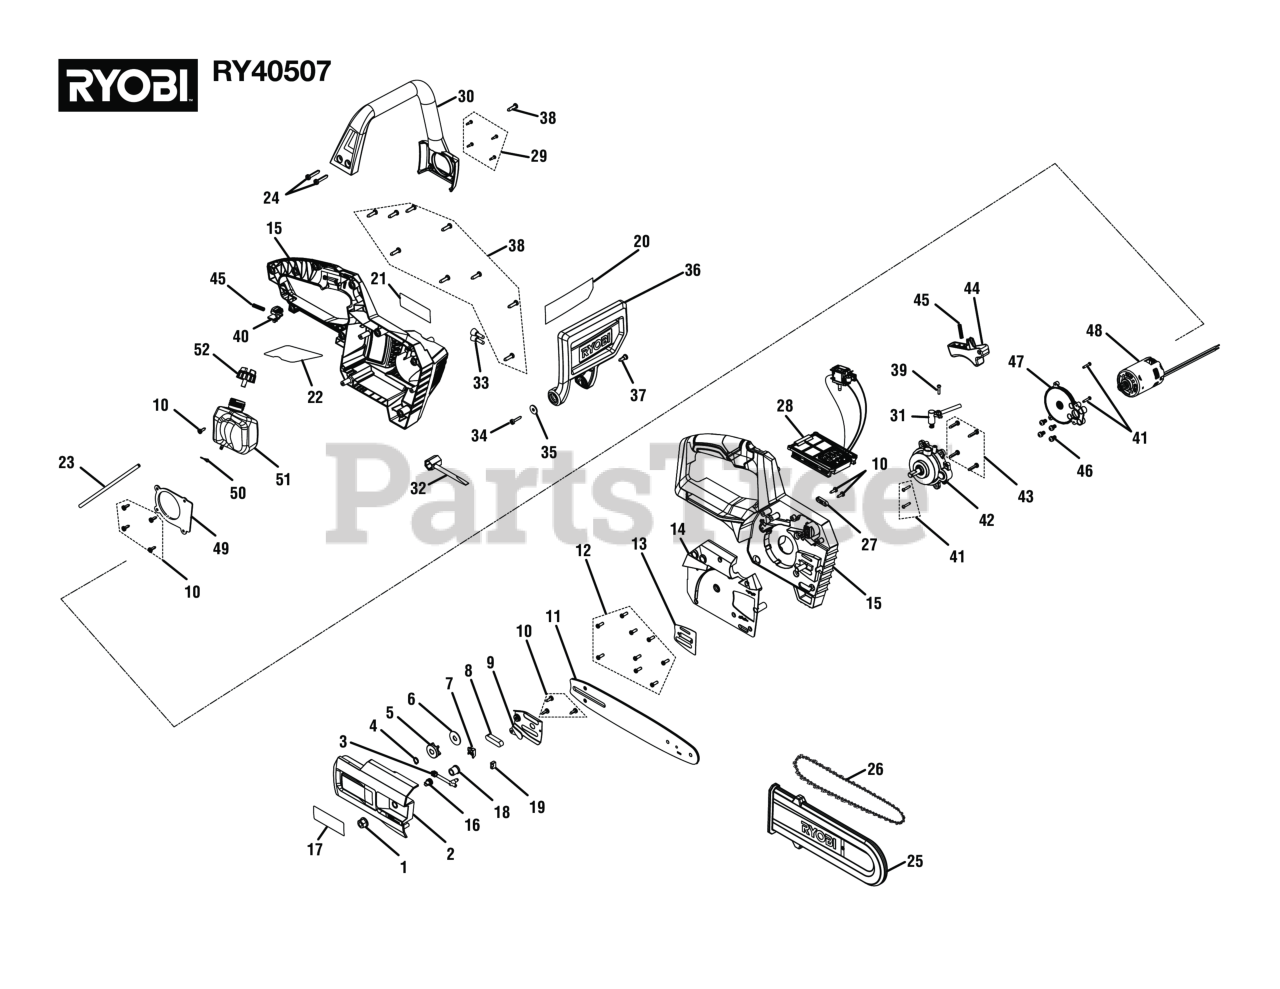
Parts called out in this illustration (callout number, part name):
1	Hex Nut (5/16-18 Flange)
2	Sprocket Cover Assembly (Inc. Key No. 17)
3	Adjust Screw Assembly
4	Retaining Ring
6	Cover Plate (Internal "D" Washer)
7	Big Pressure Plate
8	Rubber Plate
9	Guide Plate
10	Screw (M4.2 x 12 mm, T20 Torx Pan Hd.)
11	Guide Bar
12	Screw, M4-18 x 12mm, T20 Torx Pan Head
13	Guide Bar Plate
14	Brake Band Cover
15	Housing Assembly (Inc. Key No. 21-22)
16	Bar Adjust Gear
17	Logo Label
18	Sprocket Cover Bushing
19	Small Pressure Plate
20	Icon Label
21	40V Label
22	Data Label
24	Screw (T20 x 20 mm)
27	Wire Press Plate
28	Battery Foot and Switch Assembly
29	Screw (M3 x 10 mm)
30	Front Handle
31	Oil Pump Assembly w/Tube
33	Wire Connector (Closed End)
34	Screw (M4 x 21 mm, T20 Torx Hd.)
35	Washer (ID5.2 x OD16 x 1.5t)
36	Front Guard Assembly (Inc. Key No. 20)
37	Screw, Torx T25, M5, Low Carbon Steel,
38	Screw (T20 x 15 mm)
39	Screw (M3.5 x 15 mm, Pan Hd.)
40	Lock Off Trigger
41	Screw (M3 x 15 mm, Pan Hd.)
42	Gear Box Base and Shaft Assembly
43	Screw (M4 x 18 mm, T20 Torx Pan Hd.)
45	Compression Spring (Trigger Lock)
46	Screw w/Washer (M5 x 8 mm, Pan Hd.)
47	Gear Box Cover Assembly
48	Motor Assembly
49	Volute Cover
50	Clip-hose
52	Oil Tank Cap Assembly
